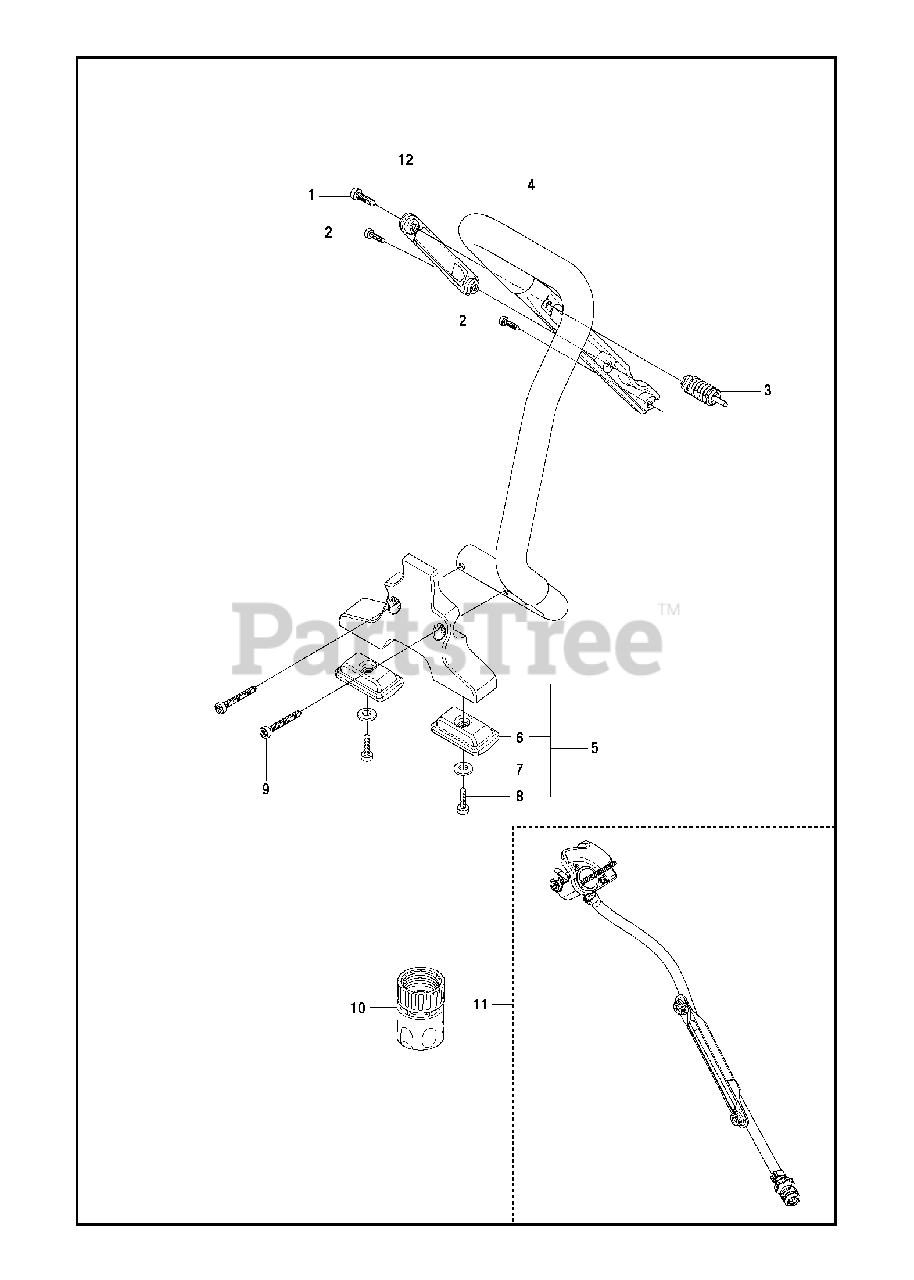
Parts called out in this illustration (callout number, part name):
1	SCREW ITXSCM
2	SCREW ITXSCT
3	ANTIVIBRATION ELEMENT
5	GROUND SUPPORT
8	SCREW ITXSCM
9	SCREW ITXSCT
10	COUPLER"1/2"""
10	COUPLER"GHT 3/4"""
11	HOSE KIT
